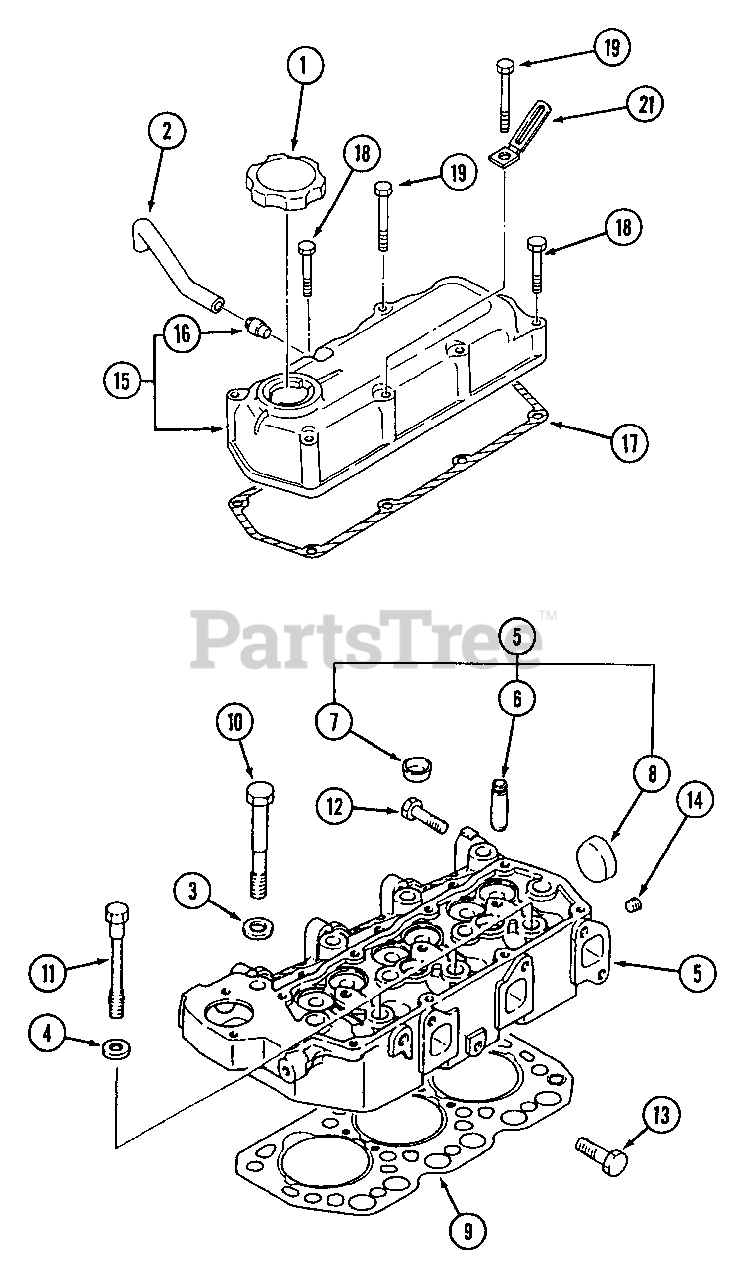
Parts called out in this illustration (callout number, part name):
1	Cap, Oil Filler
2	Pipe, Air Breather
3	Washer, Head Bolt
4	Washer, Head Bolt
5	Head Ass'y., Cylinder
6	Guide, Valve
7	Cap, Sealing
8	Plug, Expansion
9	Gasket, Cylinder Head
10	Bolt, Cylinder Head
11	Bolt, Cylinder Head
14	Plug, Taper
15	Cover Ass'y., Rocker
16	Pipe
17	Gasket, Rocker Cover
